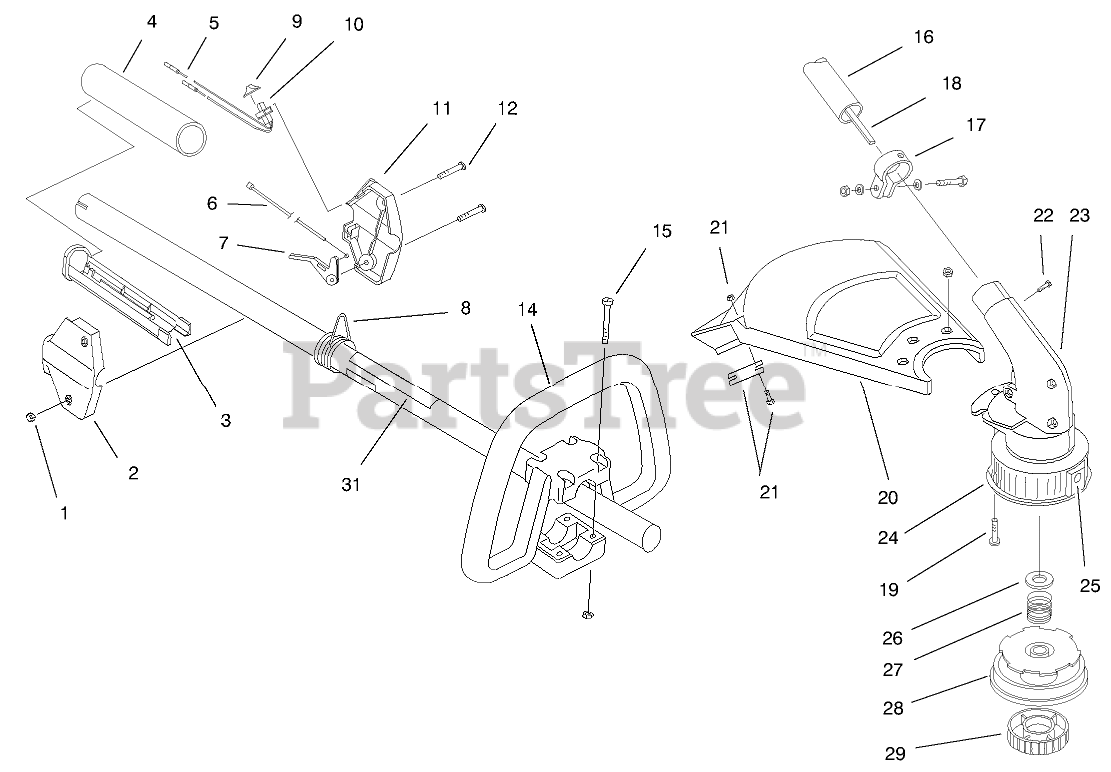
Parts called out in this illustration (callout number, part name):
1	NUT-LOCK, NI
2	RH HOUSING
3	TROUGH 1"
4	GRIP - RUBBER
9	SWITCH COVER
10	SWITCH
11	LH HOUSING
15	HARDWARE - HANDLE
17	CLAMP ASM - UPPER
19	ASM - GUARD MTG SCREW
21	BLADE ASM
22	ANTI-ROTATION SCREW
24	OUTER SPOOL EYELET ASM
25	EYELET
26	RETAINER WASHER
27	SPRING
28	REEL - INNER
